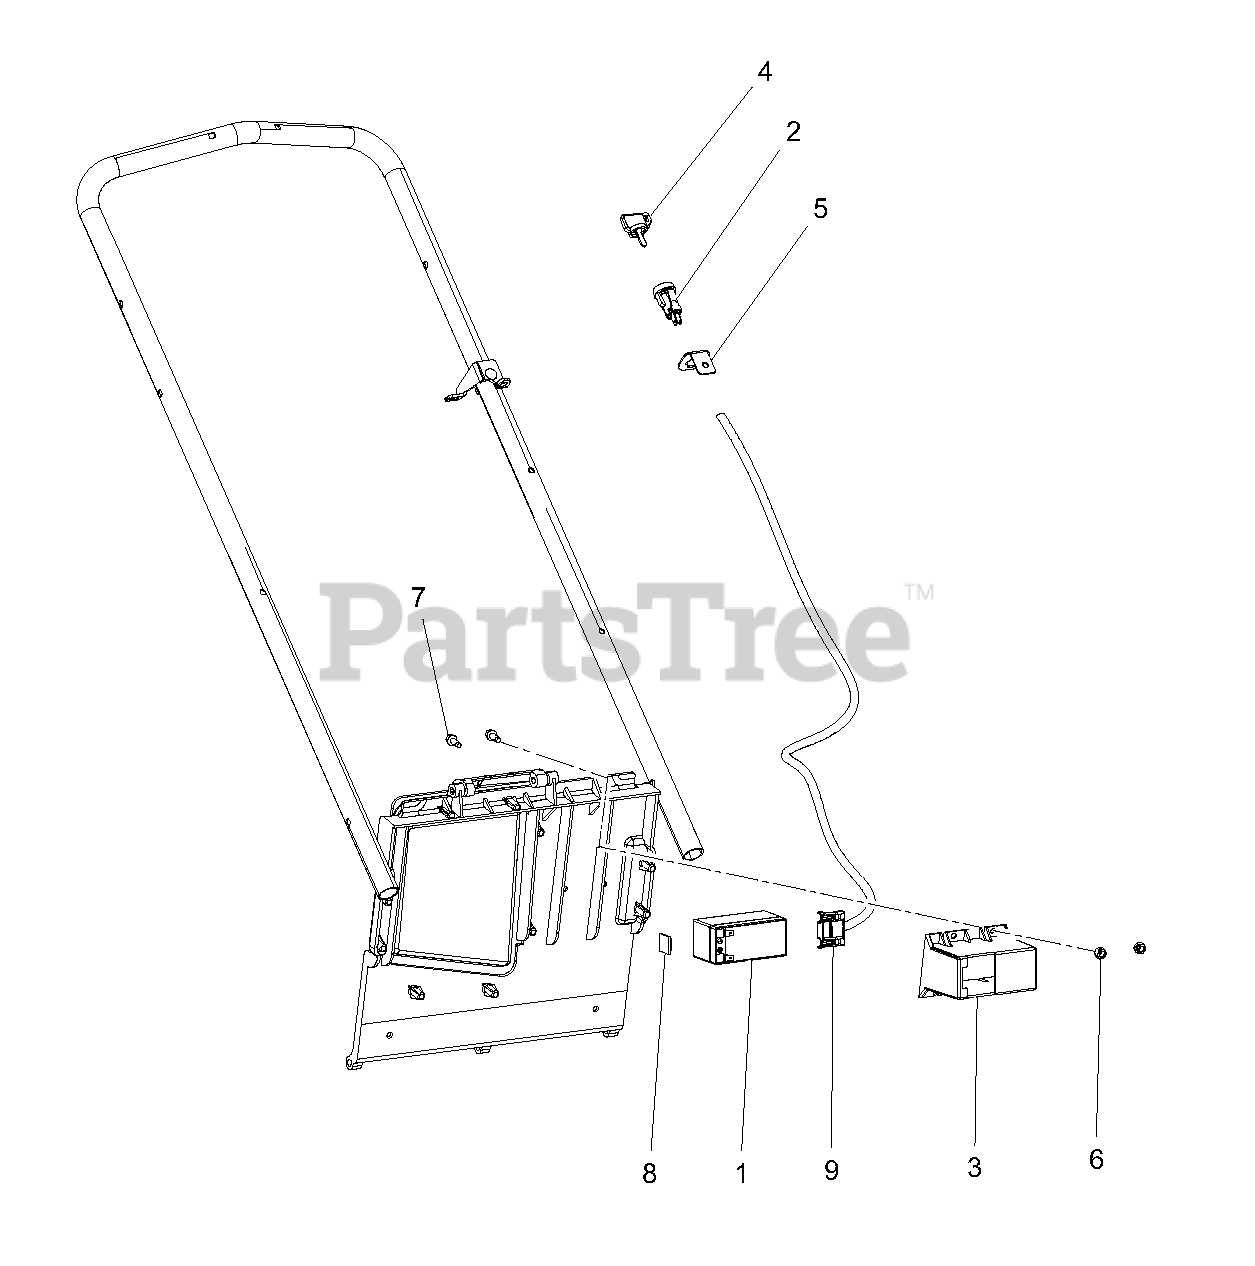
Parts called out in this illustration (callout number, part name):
1	BATTERY, SMALL AGM
2	SWITCH, KEY
3	COVER, BATTERY
4	KEY, LM ELEC START
5	BRKT, KEY SWITCH
6	@NUT-LK-CTR .25-20 YWZC
7	SCR-TAP .25-20X.62 HWH TR YWZ
9	HARNESS, ELEC START - SUBARU
10	CHARGER, BATTERY (N/S)
